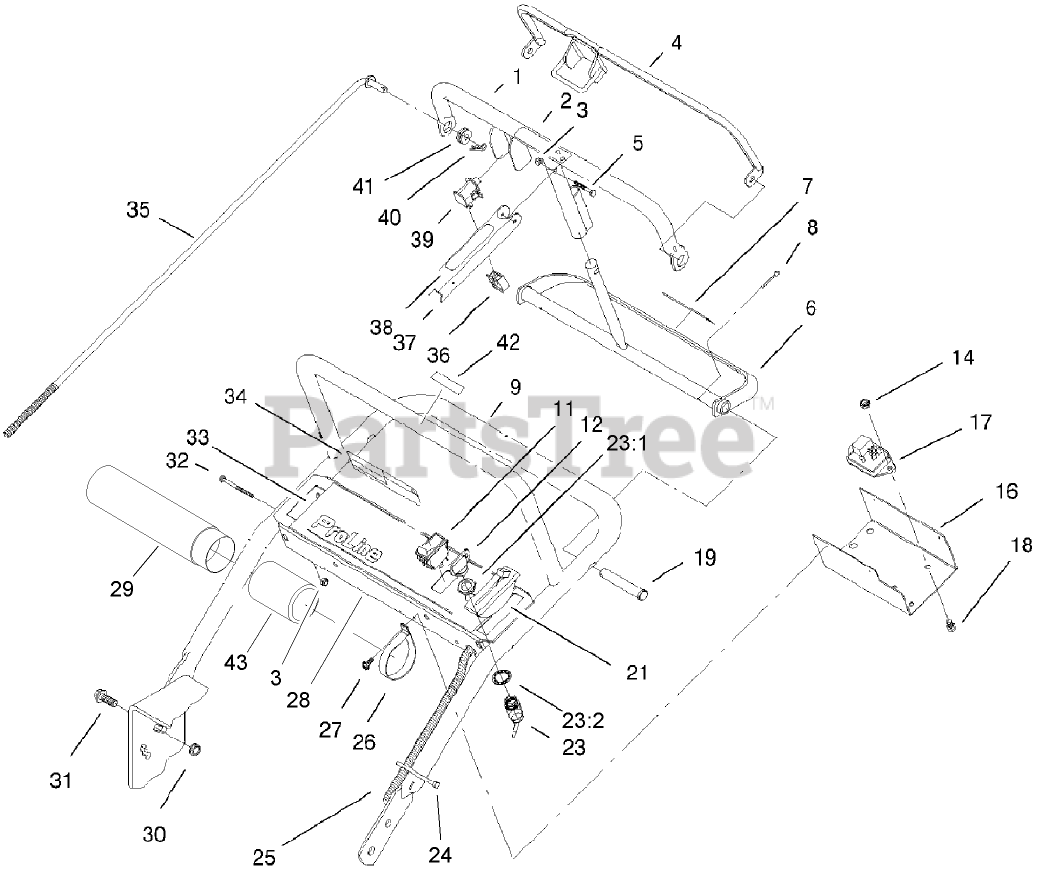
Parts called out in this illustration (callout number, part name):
1	BAR-CONTROL
2	DECAL
3	NUT-LOCK, NI
5	SCREW-SHH
6	PIVOT-CONTROL
7	DECAL
8	PIN-COTTER
9	Handle-Upper
11	SWITCH-PTO
12	KEY-IGNITION
14	NUT-LOCK, NI
16	PANEL-BOTTOM
17	MODULE-DELAY
18	SCREW-HH
19	PIN-CLEVIS
21	CONTROL-THROTTLE
23	SWITCH-ON / OFF
23:1	NUT-HH
23:2	WASHER-TOOTH, INTERNAL
24	TIE-CABLE
25	HARNESS-WIRE
26	CLAMP-R
27	SCREW-HWHTF
28	PANEL-CONTROL
29	TUBE-MANUAL
30	NUT-HF
31	SCREW-HHF
32	SCREW-SHH
33	DECAL-PANEL, CONTROL
34	DECAL-DANGER
35	ROD-CONTROL
36	CONNECTOR-BODY
37	LEVER-BRAKE, PARKING
38	DECAL-LEVER, PARKING
39	SWITCH-BAIL
40	PIN-COTTER
41	GROMMET-RUBBER
42	DECAL-PROTECTION, EAR
43	CAP-HOUSING
